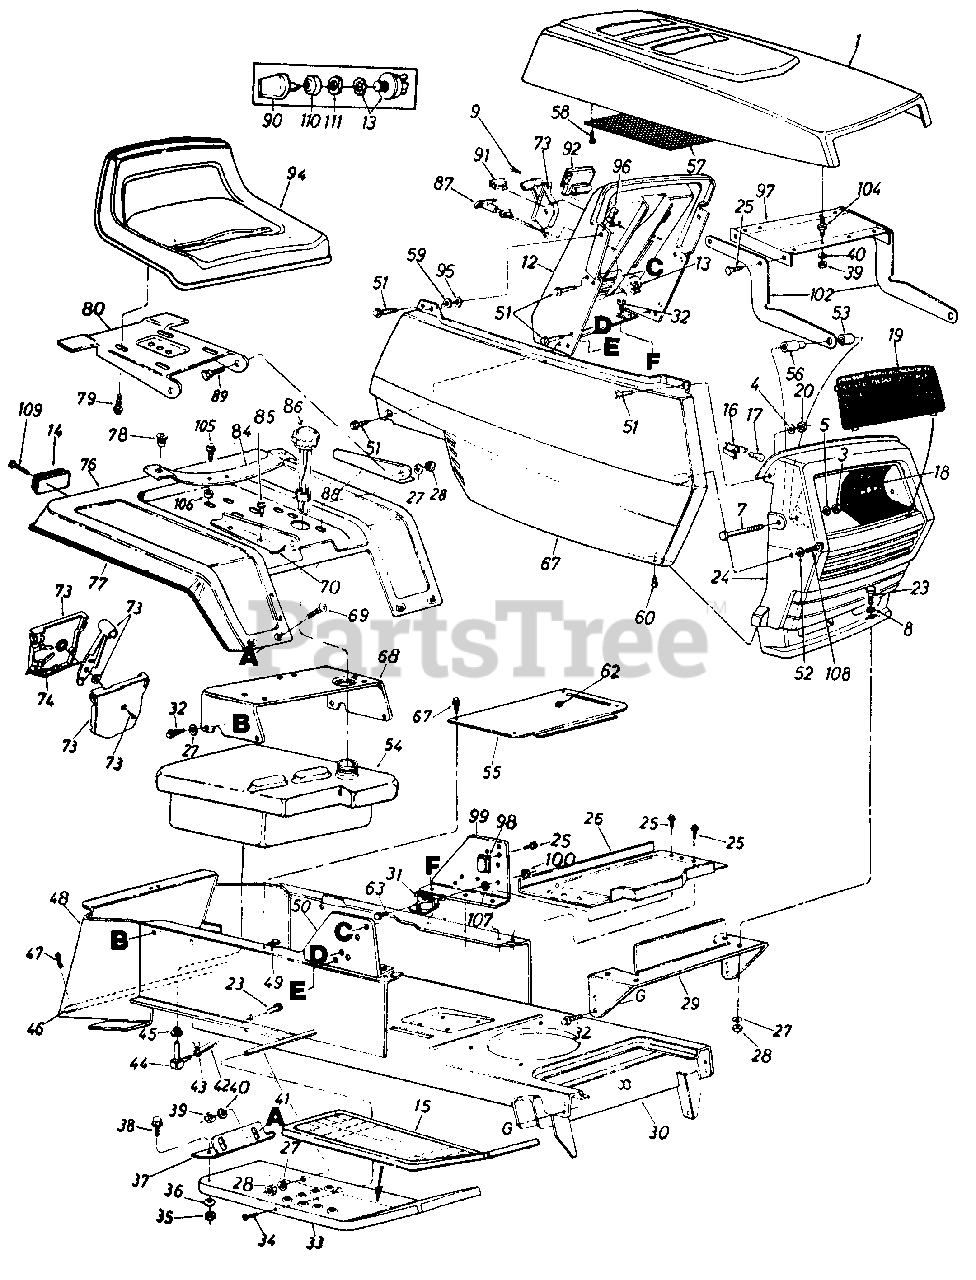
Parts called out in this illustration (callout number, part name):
4	Flat Wash. .281" I.D. x .5" O.D.
5	Fl-Wash. 5/16" I.D. x 518" O.D.
7	Hex Bolt 5/16-18 x 2.5" Lg.
8	Fl-Wash..344" I.D.
9	Truss Mach. AB-Tap Scr. #10 x .50" Lg.
13	Ignition Switch
16	Socket
17	Lamp
18	Reflector Label
19	Lens
20	Hex L-Nut 1/4-20 Thd.
23	Hex Bolt 5/16-18 x .75" Lg.*
24	Grille
25	Hex Wash. Hd. Scr. 1/4" x .50" Lg.
26	Battery Plate
27	L-Wash. 5116" I.D.
28	Hex Nut 5/16-18 Thd.
29	Grille Mounting Bracket
30	Lower Frame Ass'y.
31	Solenoid
32	Hex Thd. Rolling Scr. 5/16-24 x .75 " Lg.
33	Running Board-R.H.
34	Truss Mach. Scr. 5/16-18 x .75" Lg."
35	Hex Nut 5/16-18 Thd.*
36	Bell-Wash. .34" I.D. x .87"
39	Hex Nut 1/4-20 Thd.*
40	L-Wash. 1/4" I.D.
41	Running Board Rod
42	Fuel Line 40" Lg.
43	Hose Clamp 318"
44	90ø Nipple
45	Bushing
47	Internal Cotterpin
50	Dash Support Brkt.-R.H.
51	Hex Wash. Hd. Tap Scr. 1/4 x .75" Lg.
52	Fl-Wash. .281" I.D. x .73" O.D.
53	Spacer.33" I.D. x .625" O.D.
55	Transmission Cover Ass'y.
56	Shld. Spacer .33" I.D. x .625" O.D.
58	Hex Wash. Hd. Tap Scr. #8 x .5" Lg.
59	Fl-Wash. .25" I.D. x .93" O.D.
60	Hex AB-Tap Scr. #10 x .5" Lg.
62	Snap Bushing
63	Hex Bolt 1/4-20 x .5 Lg.
67	Truss Mach. "B" Tap Scr. #10 x .50" Lg.
68	Seat Mounting Channel
69	Carriage Bolt 1/4-20 x .50"
70	Seat Bracket-R.H.
73	Throttle Control Box Ass'y.
74	Throttle Control Wire
76	Rear Fender
77	Trim Strip-81" Lg.
79	Hex Wash. Hd. AB-Tap Scr. 3/8 x .75" Lg.
80	Seat Pivot Bracket
84	Seat Spring
85	Hex Wash. Hd. Self-Tap Scr. 5/16-18 x .50" Lg.
86	Gas Cap w/Gauge
87	Choke Control Comp.
88	Seat Bracket-L.H.
89	Shld. Bolt .437" Dia. x .162"
90	Ignition Key
91	Light Switch
92	Ammeter
94	Seat Ass'y.
95	Bolt Retainer
96	Speed Nut 1/4-20 Thd.
97	Hood Plate
98	Circuit Breaker
99	Dash Support Brkt.-L.H.
100	Hex Sems Nut 1/4-20 Thd.
102	Hood Hinge
104	Double Ended Stud 1/4-20 Thd.
105	Hex Tap Scr. 5/16-18 x 1.25" Lg.
106	Spacer.38" I.D.
107	Ext. L-Wash. .44" I.D.
108	Hex Wash. B-Tap Scr. 1/4 x.62" Lg.
109	Truss Hd. AB-Tap Scr. #6 x .62" Lg .
110	Ignition Switch Cap
111	Ignition Switch Nut
